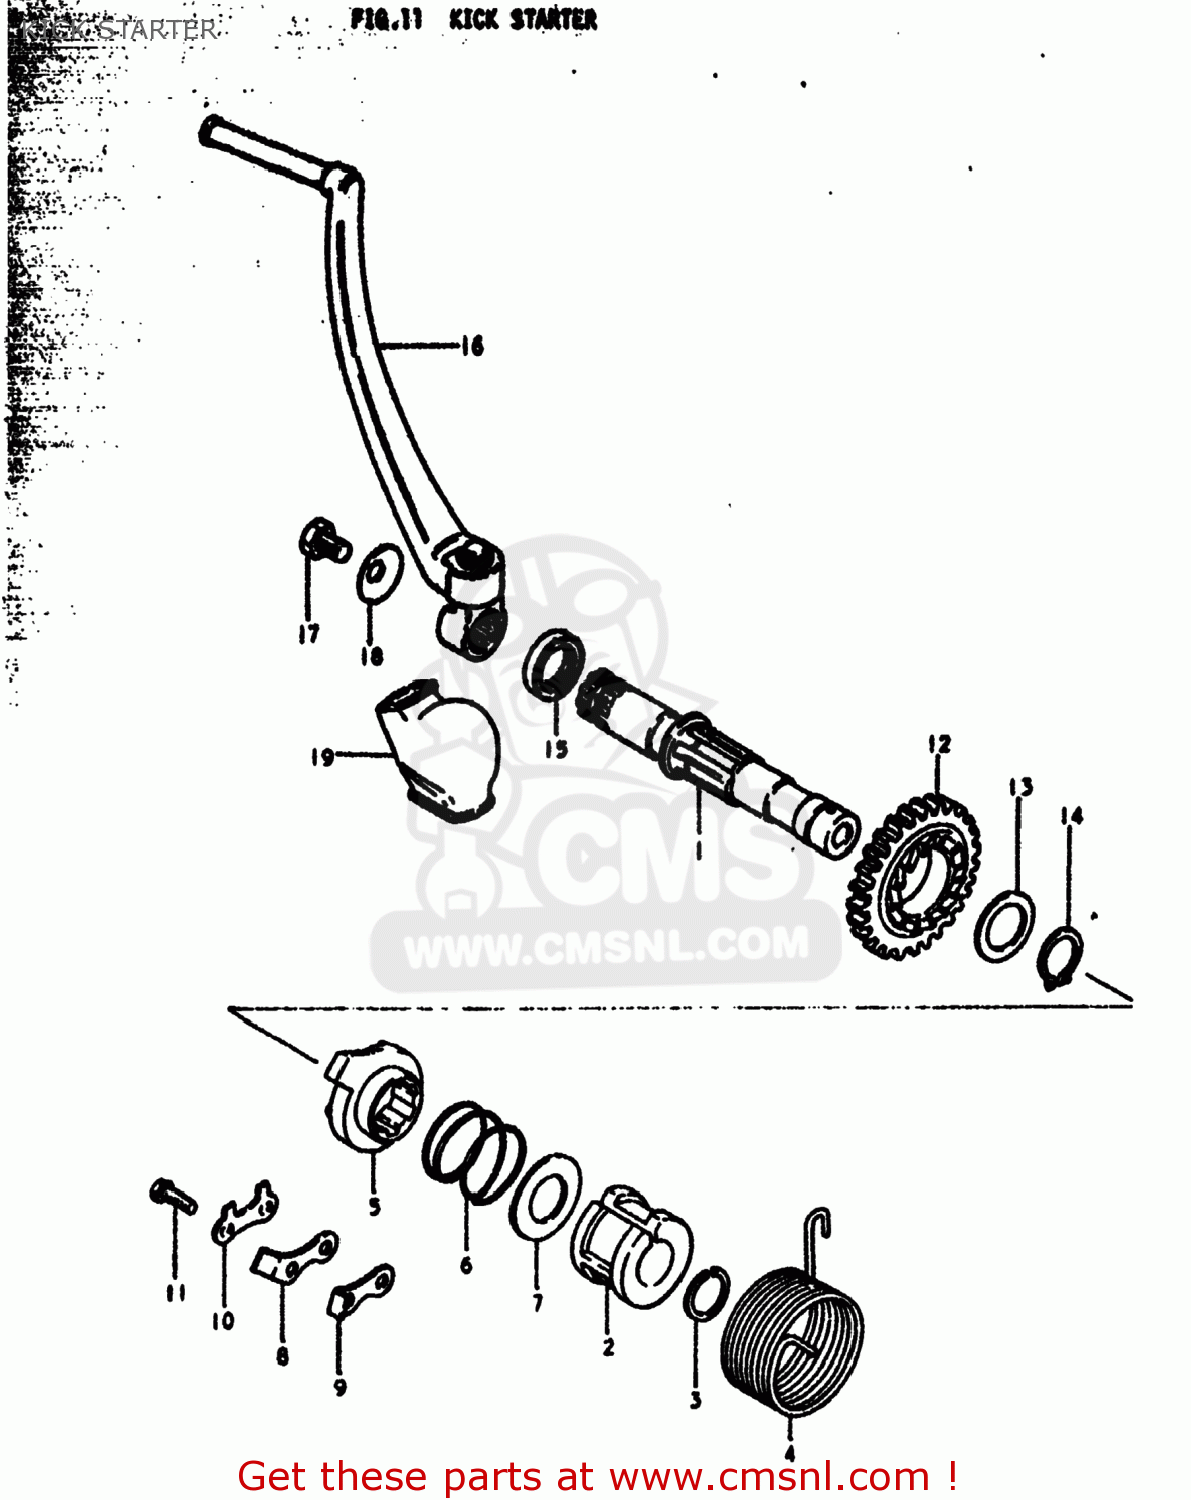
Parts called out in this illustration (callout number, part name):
1	SHAFT,KICK STARTER
2	GUIDE,KICK STARTER SFT SPRING
3	CIRCLIP
4	SPRING
5	STARTER,KICK
6	SPRING
7	WASHER
8	GUIDE,KICK STARTER
9	STOPPER,KICK STARTER
10	WASHER
11	BOLT, UPPER
12	GEAR,KICK STARTER DRIVE
13	WASHER
14	CIRCLIP
15	SEAL,OIL(20X27X5)
16	LEVER ASSEMBLY,KICK STARTER
17	BOLT
18	WASHER (8X34X1)
19	COVER,KICK LEVER JOINT
